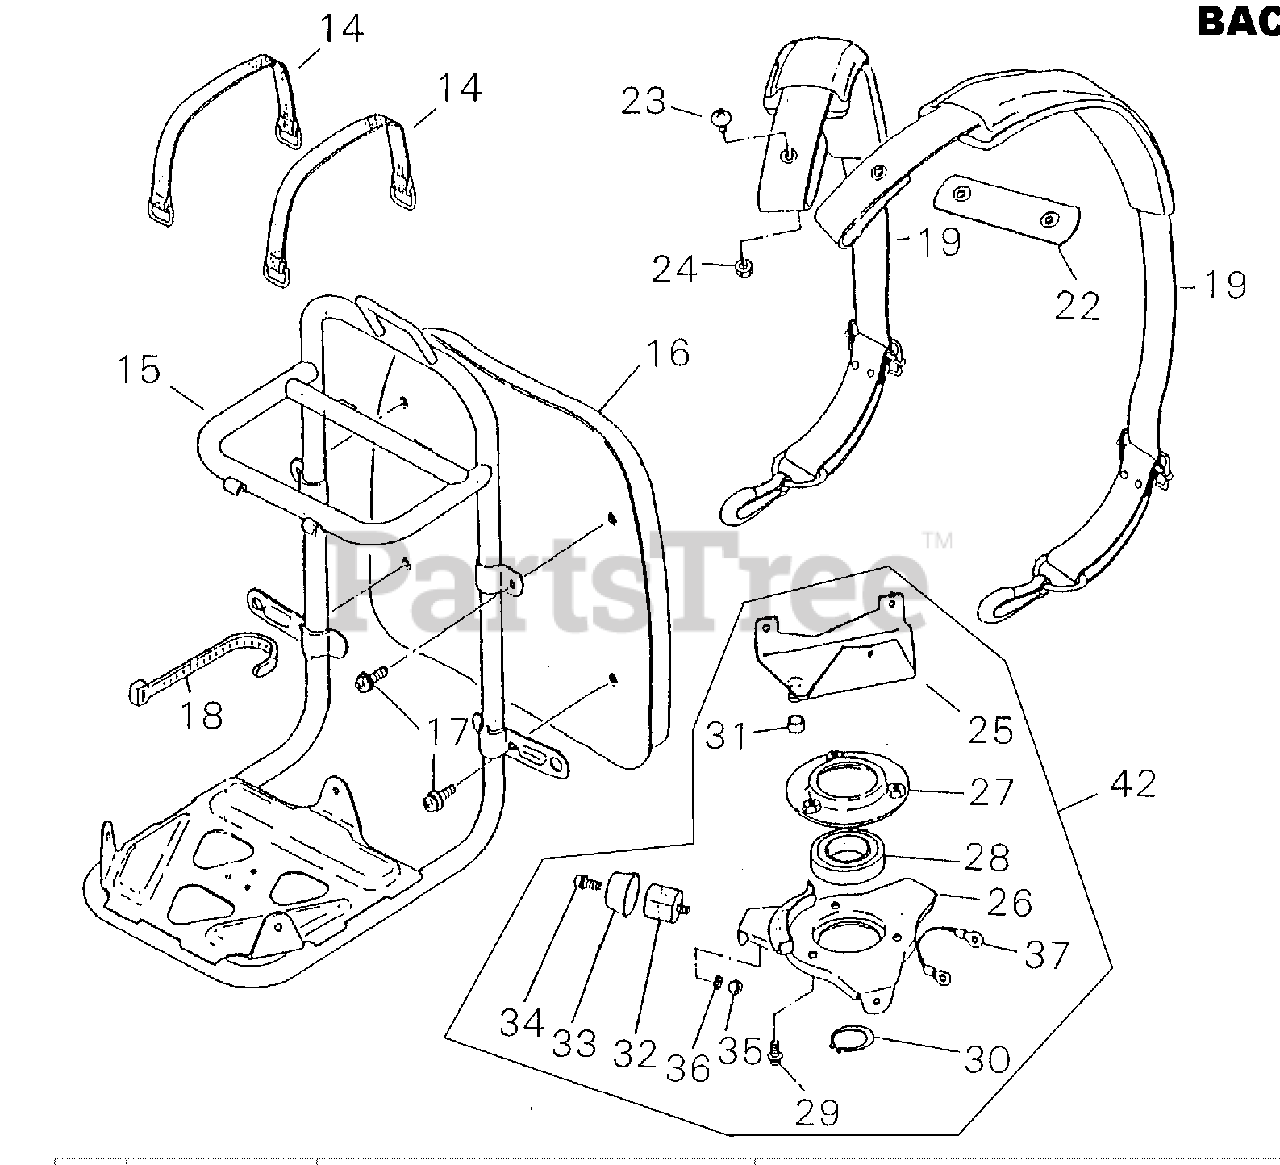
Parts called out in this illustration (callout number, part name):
14	STRAP, FUEL TANK
15	FRAME, BACKPACK
16	PAD
17	SCREW M5×12
18	CLAMP
19	HARNESS ASSY
22	BAND, HARNESS
23	SCREW, TRUSS M6×14
24	NUT, LOCK M6
25	BRACKET, UPPER
26	BRACKET, LOWER
27	RETAINER
28	BEARING, BALL 6005ZZ
29	SCREW M5×10
30	RING, SNAP Ø25
31	CUSHION
32	CUSHION, AV 5
33	CAP, CUSHION
34	SCREW M5×10
35	NUT M5
36	WASHER, SPRING 5
37	LEAD - GROUND
42	BRACKET ASSY
